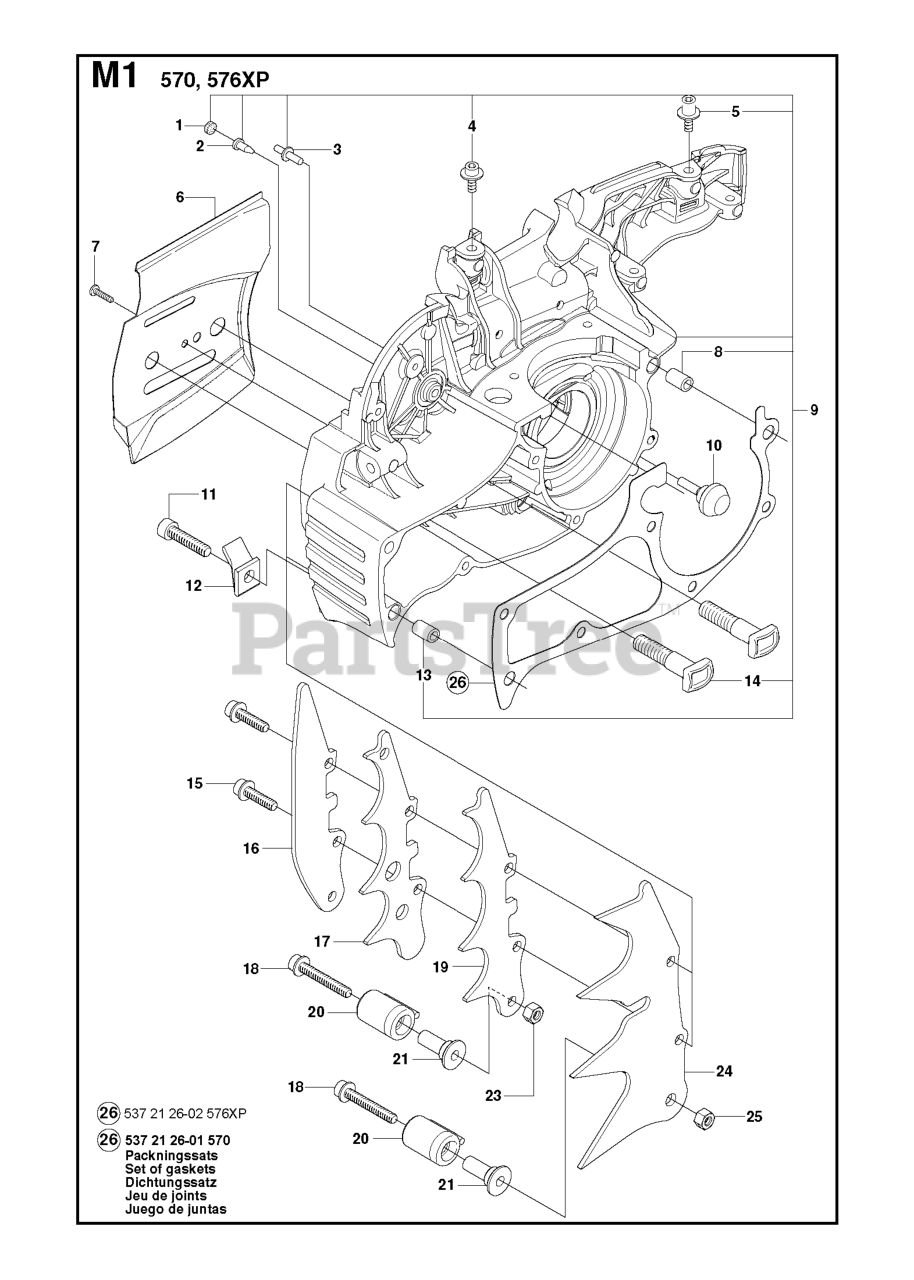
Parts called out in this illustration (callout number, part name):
1	PLUG
2	VALVE-CHECK (DUCKBILL)
4	SCREW IHSCM
5	SCREW IHSCM
9	RP CRANKCASE ASSEMBLY
9	CRANKCASE ASSY
12	CHAIN CATCHER
17	FELLING DOG
18	SCREW
18	SCREW IHSCFM
19	FELLING DOG
21	CHAIN CATCHER
24	FELLING DOG
26	GASKET SET
26	GASKET KIT
